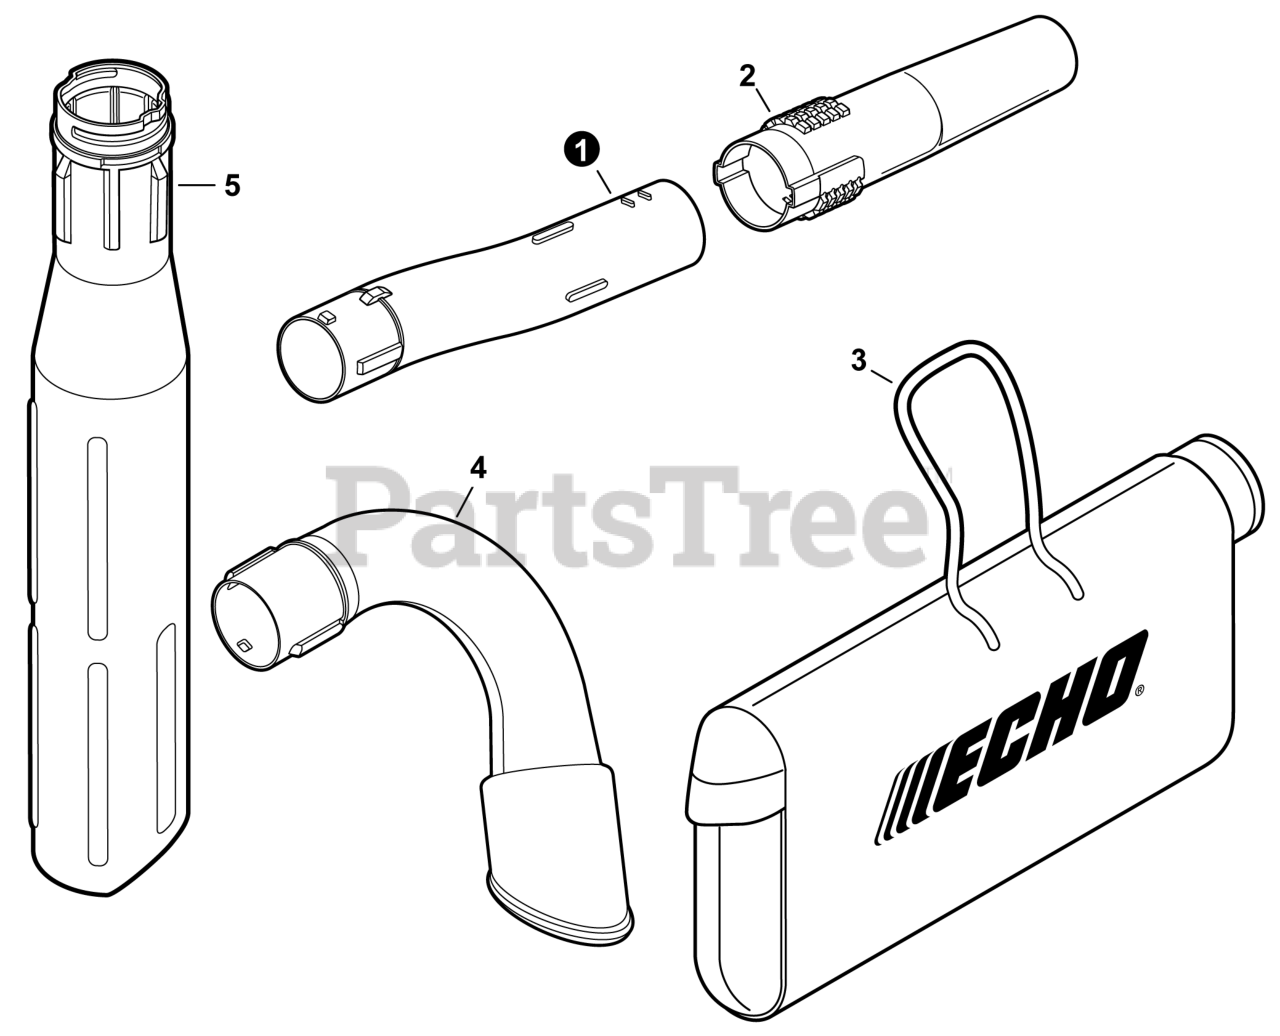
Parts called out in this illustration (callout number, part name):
1	TUBE, BLOWER - CURVED
2	TUBE, BLOWER - ROUND NOZZLE
3	BAG, DEBRIS
4	TUBE, BLOWER - ELBOW
5	TUBE, BLOWER - SUCTION
